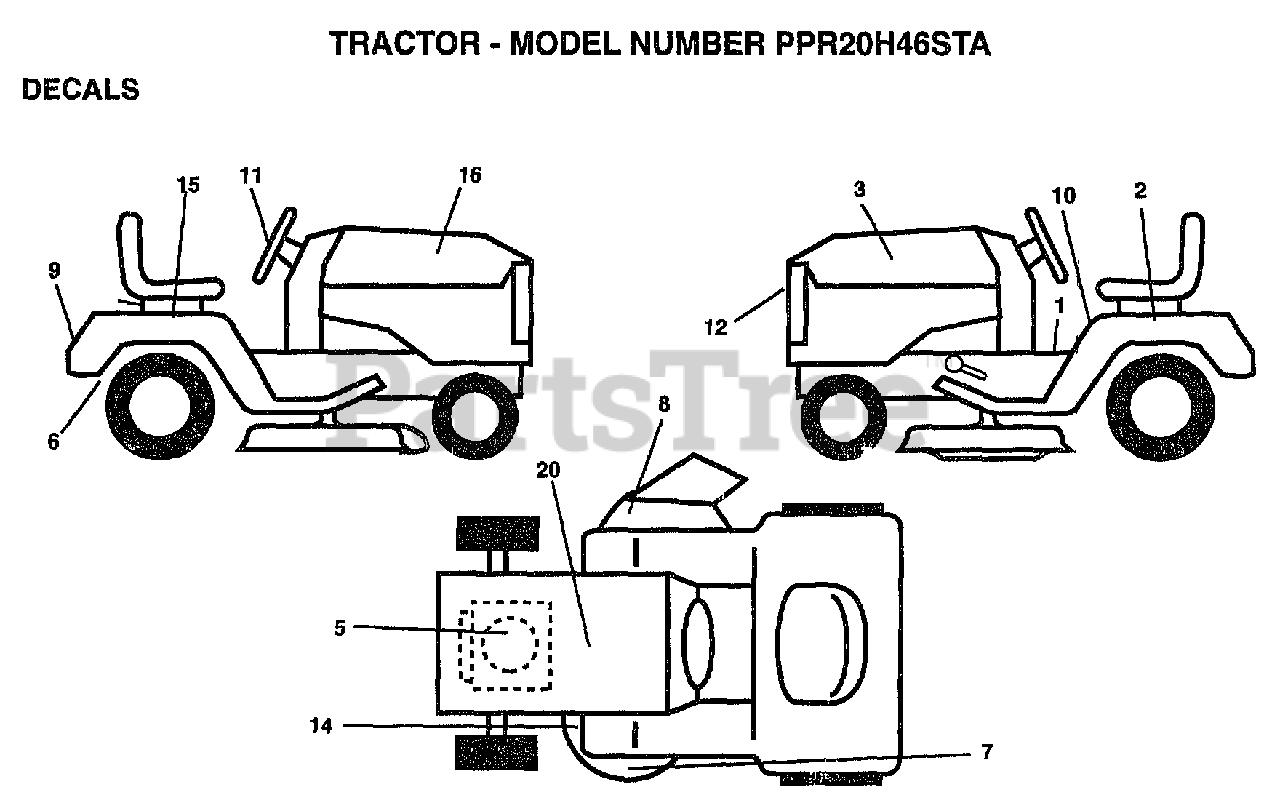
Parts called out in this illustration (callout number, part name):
1	DECAL SADDLE OPER
2	DECAL.FENDER.SD.AUTO
3	DECAL.HOOD.LH
5	DECAL .B&S.20HP
6	DECAL DRAWBAR LH
7	DECAL T
8	"DECAL, WARNING"
9	DECAL.FENDER.LOGO
10	DECAL.CAUT.ENG/FR
11	DECAL.INS.WHL.STRG
12	DECAL.GRILLE.
15	DECAL.FENDER.SD.RH.
16	DECAL.HOOD.RH
20	DECAL.BATRY.3-3908
